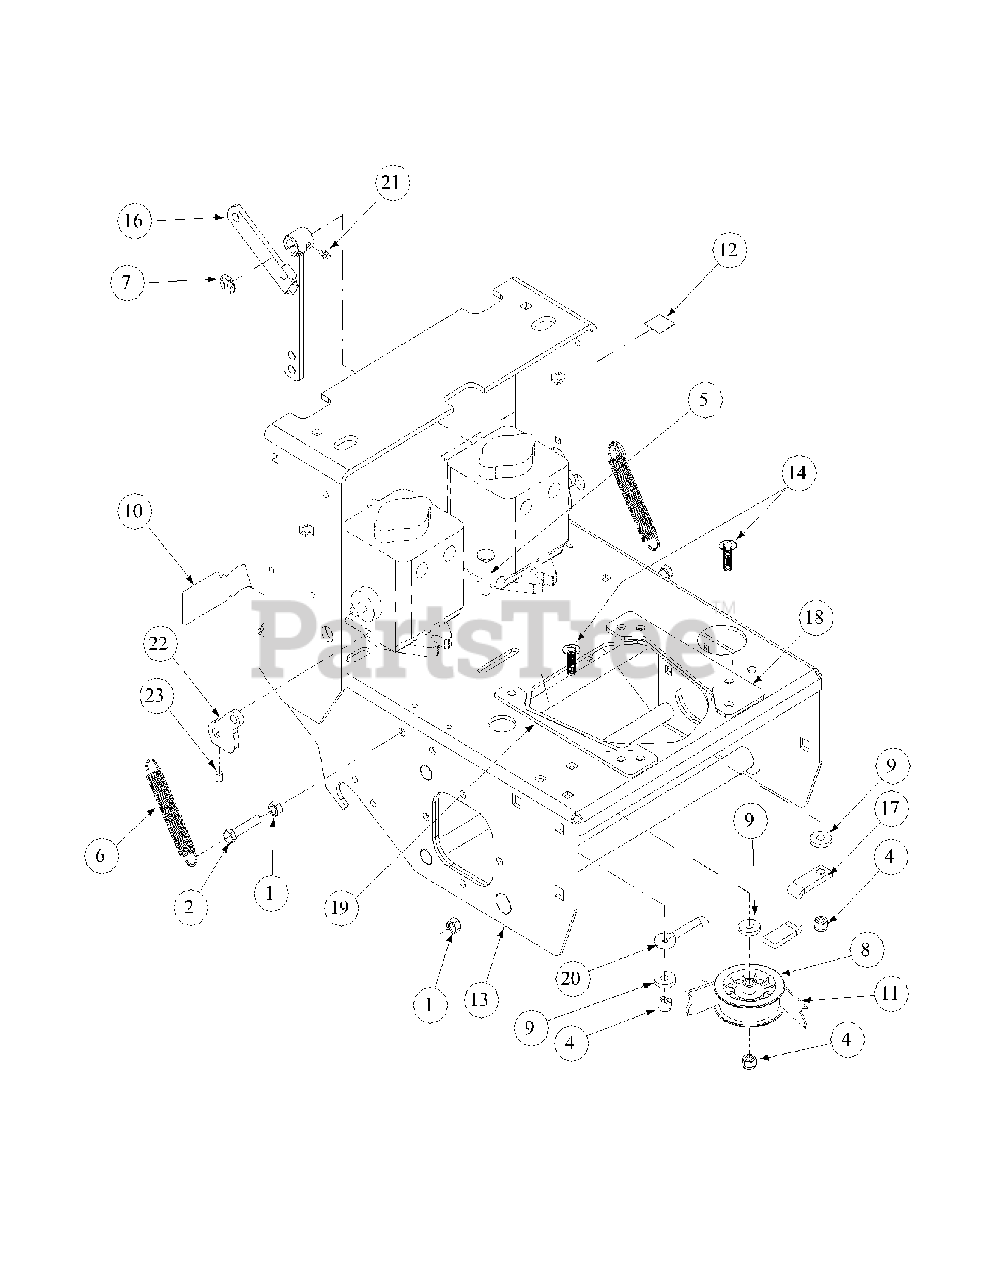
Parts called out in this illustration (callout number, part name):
1	Nut, Hex, 3/8-16 Grade C
2	Cap Screw, 3/8-16 x 1-3/4" Grade 5
3	Nut, 5/16-18, Nylock
4	Nut, L, Nylon Insert, 3/8-16 Grade A
5	Carriage Bolt, 3/8-16 x 2 Grade 5
6	Spring, Music Wire, LE-093G-9, Plated 2
7	E-Ring, 5/8" #5113-62
8	Pulley, Flat Idler W/Adaptor
9	Washer, Idler
10	Decal, "Made In America"
11	Belt, Hydro Pump
12	Label, Mower, Warn, Open Belt Drive
13	Engine Base Assembly, Hydro
14	Carriage Bolt, 3/8-16 x 1.25 Grade 5
16	Bellcrank Clutch
17	Belt Guide, Engine, 36/42/48
18	Spacer, Engine, Right Hand
19	Spacer, Engine, Left Hand
20	Belt Guide, 3.375
21	Grease Fitting, 1/4-28 x 3/16 STR
22	Pump Lever
23	Set Screw, 5/16-24 x 1.25
